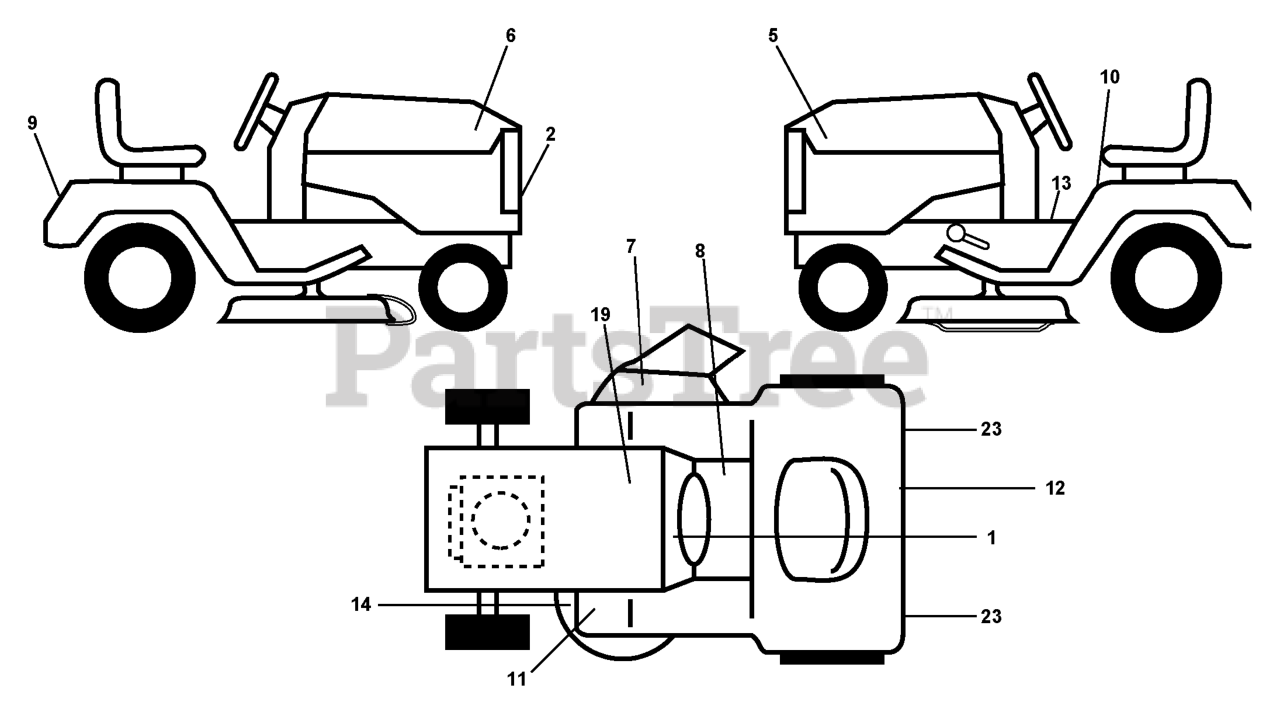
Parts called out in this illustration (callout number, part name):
2	DECAL.GRILLE.HUSQ
5	DECAL, HOOD LH GTH220 HYDRO
6	DECAL HOOD RH GTH220 HYDRO
7	DECAL WARNING (ENGLISH/FRENCH)
8	DECAL PARK BRAKE
9	Decal, Fender
10	DECAL CAUTION
12	DECAL D-BAR
19	DECAL, BATTERY DANGER
23	REFLECTOR-TAIL YT
